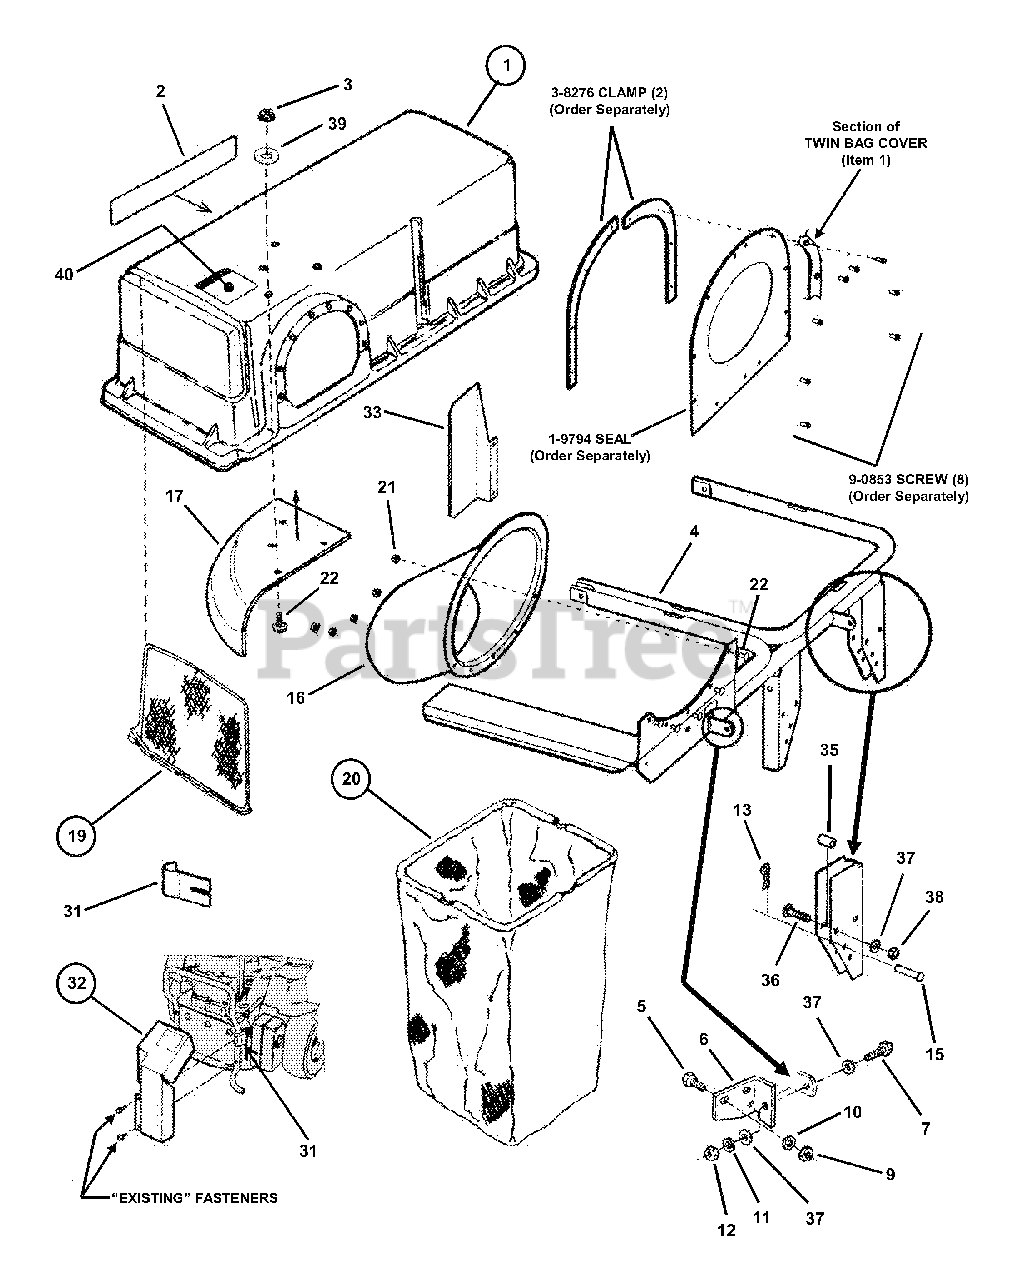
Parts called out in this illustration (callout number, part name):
1	ASS'Y, Cover
2	DECAL, Snapper
3	NUT, 1/4-20 Hex
4	WELDMENT, Frame
5	SCREW, 1/4-28 x 3/4"
6	HINGE, Top
7	SCREW, 5/16-24 x 1"
9	NUT, 1/4-28 Hex
10	WASHER, 1/4" Lock
11	WASHER, 5/16" Split
12	NUT, 5/16-24 Hex Center Lock
13	PIN, 3/32 x 1-1/2" Hair
15	PIN, 5/16 x 1-11/16" Clevis
16	INLET, Twin Bagger
17	SECTOR
19	ASS'Y, Screen (indented items)
20	ASS'Y, Bag (indented items)
21	NUT, 1/4-20 Hex Flange
22	BOLT, 1/4-20 x 1/2" Carriage
31	SUPPORT, Bumper
32	ASS'Y, Debris Shield
33	GUARD, Muffler
35	PAD, Bumper Mount
36	BOLT, 5/16-18 x 1-1/2" Carr.
37	WASHER, 5/16" Flat
38	NUT, 5/16-18 Hex Ctr. Lock
39	WASHER, 1/4" Flat
40	DECAL, Warning
